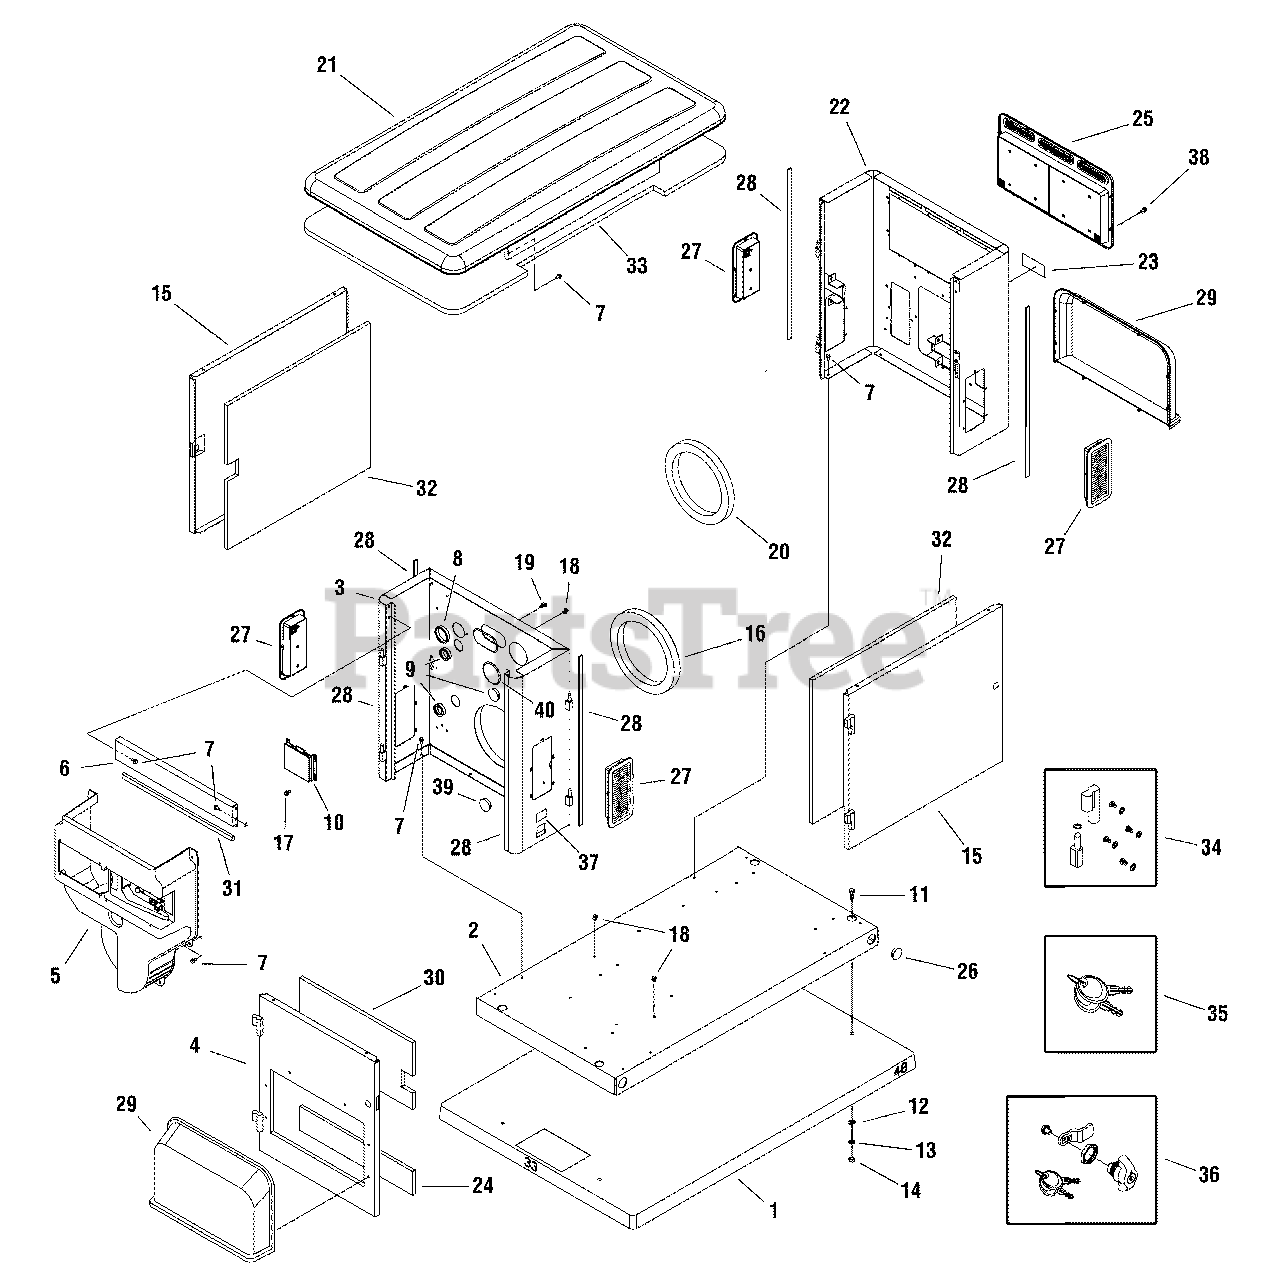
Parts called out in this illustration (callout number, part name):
3	BULKHEAD, Engine
4	DOOR
5	DUCT
6	SUPPORT, Rail
7	BOLT
10	REGULATOR-VOLTAGE
11	* CAPSCREW, Hex Head, 3/8-16 x 1
12	* WASHER, Flat, 3/8-M10
13	* WASHER, Lock, 3/8
14	* NUT-3/8-16
15	DOOR
16	SEAL, Foam
18	MOUNT, Tie wrap
20	SEAL, Foam
21	ROOF
22	BULKHEAD, Alternator
29	COVER, Air Intake
37	DECAL
